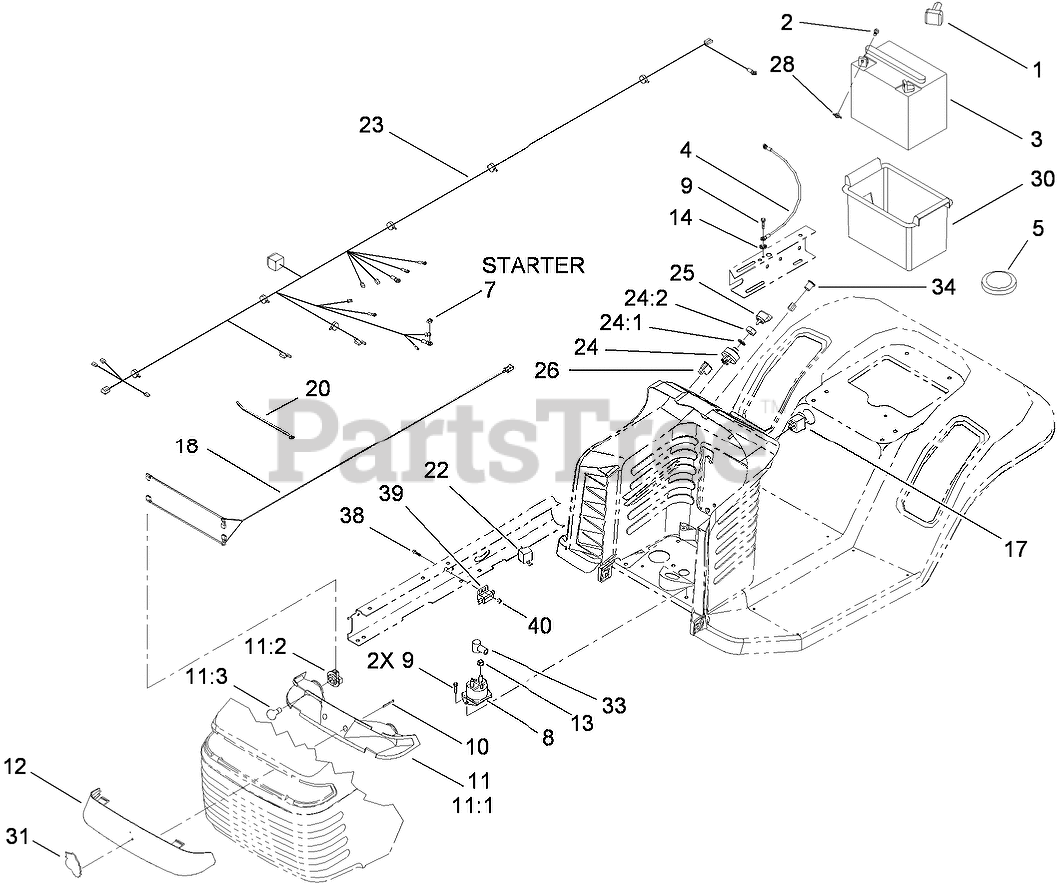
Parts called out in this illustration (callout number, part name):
1	BOOT-TERMINAL
2	SCREW-HH
3	BATTERY-155 CCA
4	WIRE ASM
5	SWITCH-SEAT
7	NUT-KEPS
8	SOLENOID-STARTER
9	SCREW-HWH
11	HEADLIGHT REFLECTOR ASM
11:1	REFLECTOR-LIGHT
11:2	SOCKET-HEADLIGHT
11:3	BULB
12	LENS-HEADLIGHT
13	NUT-KEPS
14	WASHER-LOCK/EXT
17	SWITCH-PTO
18	HARNESS-HEADLIGHT
20	TIE-CABLE
22	RELAY
23	HARNESS-WIRE
24	Key Switch ASM
24:1	WASHER-TOOTH, INTERNAL
24:2	NUT-HH
25	KEY-IGNITION
26	SWITCH-ROCKER
28	NUT-WING
30	BOX-BATTERY
31	EMBLEM
33	BOOT-INSULATOR, TERMINAL
34	LIGHT-INDICATOR
38	SCREW-HSH
39	SWITCH-POLE, SINGLE
40	NUT-LOCK, NI
